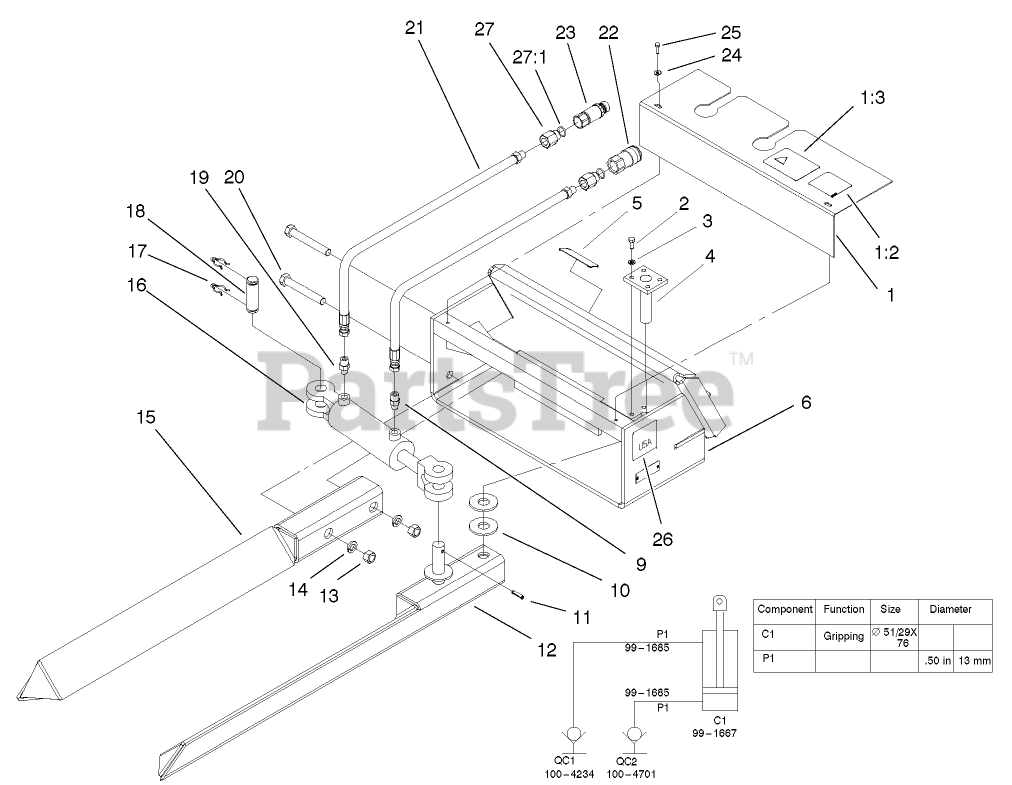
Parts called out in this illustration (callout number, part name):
1	SHIELD ASM
1:2	DECAL-WARNING
1:3	DECAL-RATING, LOAD
2	SCREW-HSH
3	WASHER-LOCK
5	DECAL-ATTACHMENT, DINGO
6	FRAME
9	CONNECTOR - STRAIGHT
10	WASHER-FLAT
11	PIN-ROLL, SLOTTED
12	ARM-PIVOT, LH
13	NUT-HEX
14	WASHER-LOCK
15	ARM-PIVOT, RH
16	CYLINDER - TREE FORK
17	CLIP - PIN
18	PIN - CYLINDER PIVOT
19	CONNECTOR-STRAIGHT ORIFICE
20	SCREW-HH
21	HYDRAULIC HOSE ASM
22	COUPLER-FACE, FLUSH
23	NIPPLE-CONNECT, PRESSURE
24	WASHER-FLAT
25	SCREW-HSH
26	DECAL
27	ADAPTER-HYD
27:1	O-RING
